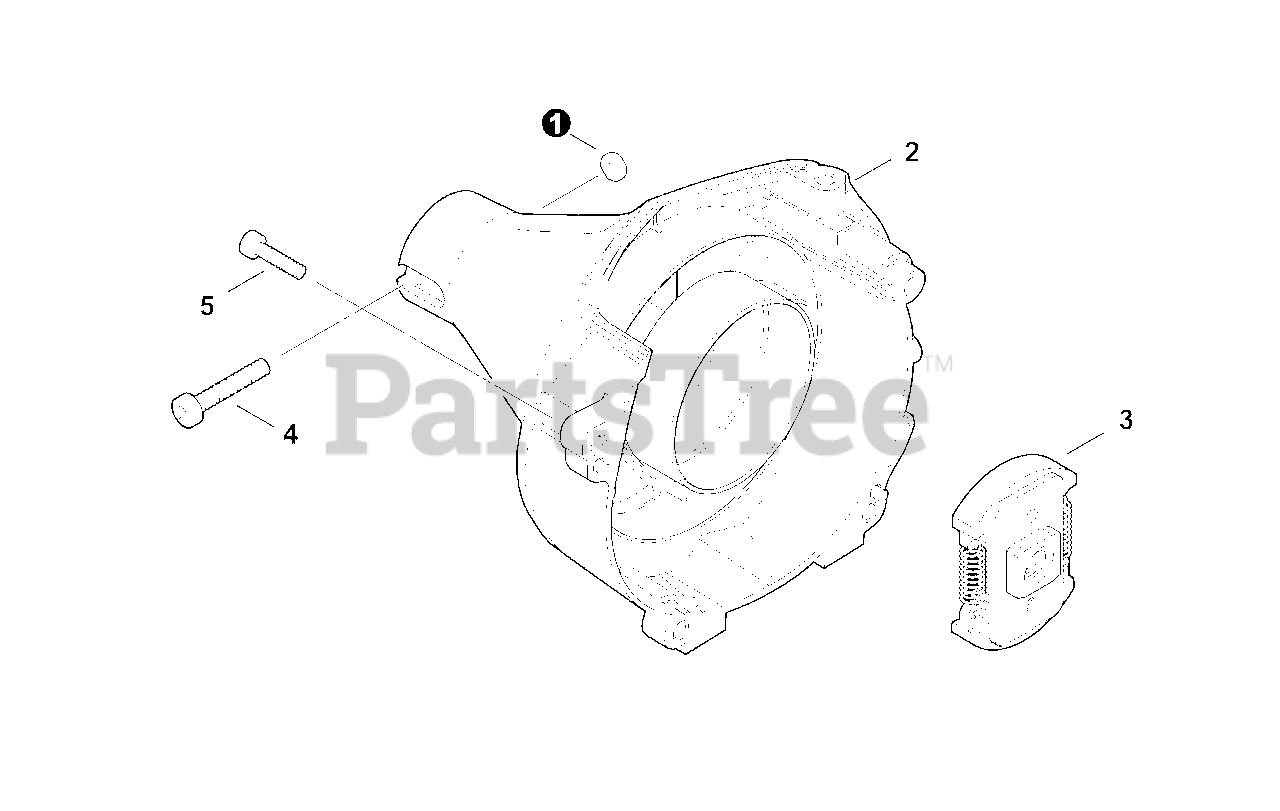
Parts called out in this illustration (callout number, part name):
1	NUT M5
2	COVER ASSY, FAN
3	CLUTCH ASSY
4	BOLT, TORX 5×25
5	BOLT, TORX 4×16
